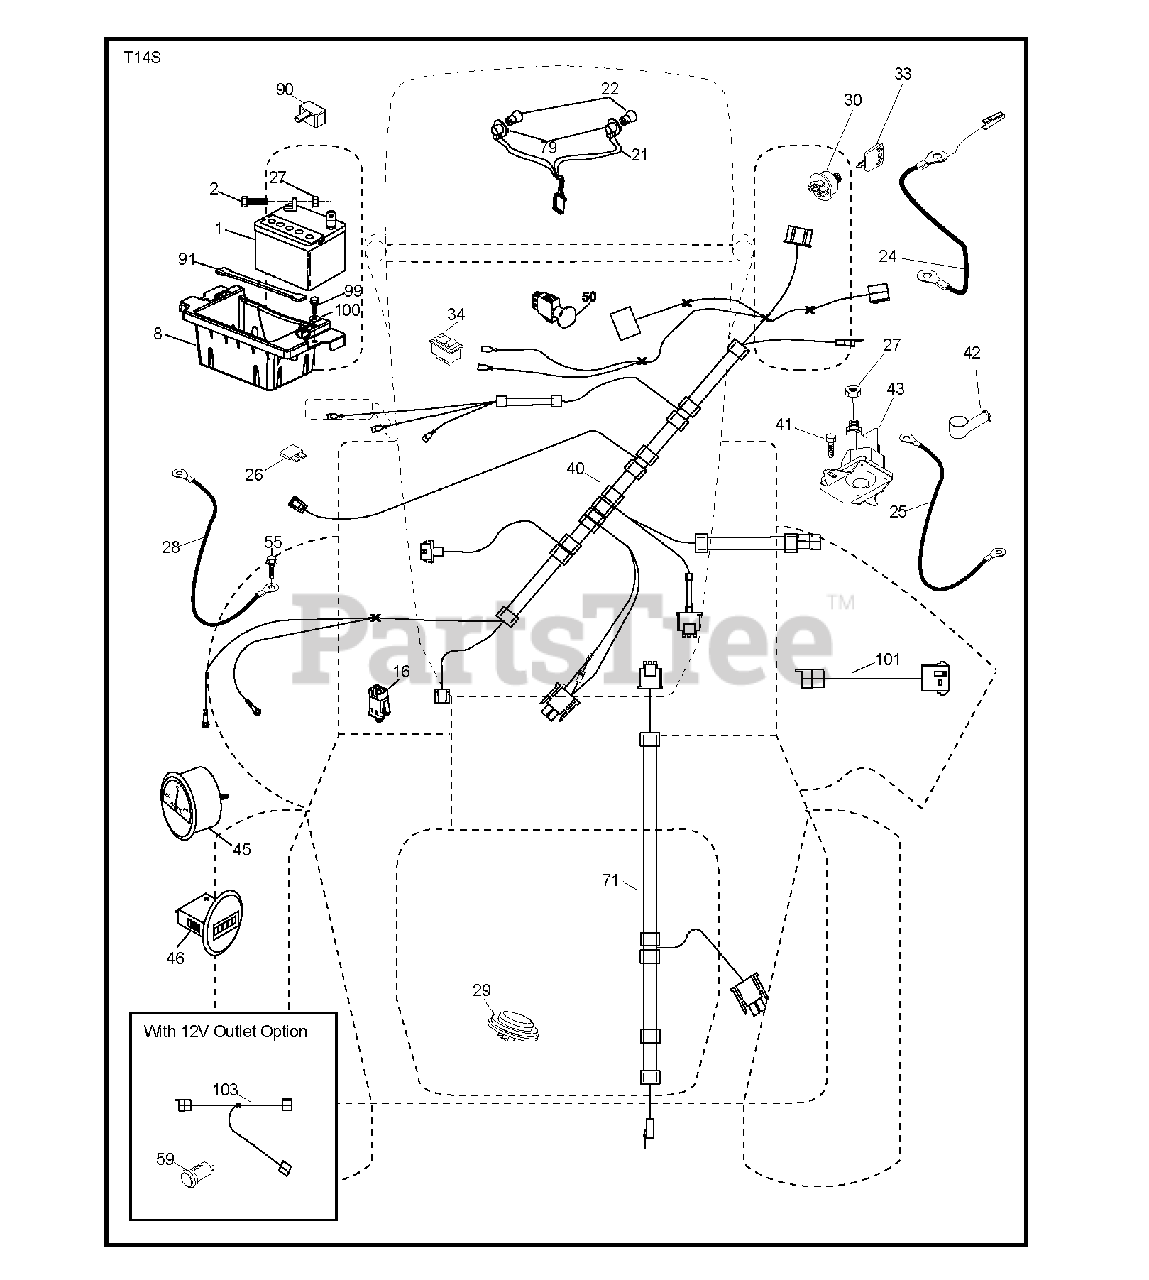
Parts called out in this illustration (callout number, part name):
1	BATTERY 12V .35 AMP
8	BOX.BATTERY.MOUNT.FRONT.LT
16	SWITCH INTERLOOK PUSH-IN
21	HARNESS.W/LIGHT SOCKET
22	LIGHTBULB
24	CABLE.BATT.POS.WIRE.TG.DA SOL
25	CABLE.START.RED.17.5".
26	FUSE 20AMP
27	NUT
28	CABLE GROUND 6 GA 21" 90T BLK
29	SWITCH.SEAT.DELTA.OPC.
30	SWITCH.IGN.DELTA.W.LGH.ROS
33	KEY.CHAIN.BLISTER.PACK.GEN.INT
34	SWITCH LT
40	HARNESS IGN. DASH
41	SCREW
42	TERMINAL COVER
43	SOLENOID.W/BRASS.PLUNG
46	HOURMETER SNAP-IN
50	PTO SWITCH
55	SCREW 5/16"
71	HARNESS-CHASSIS SUB
79	BULB HOLDER ASM.
90	COVER.TERMINAL.BATTERY
91	STRAP, BATTERY MOUNT
99	SCREW HEXWSHR 1/4-20X3/4
101	PIGTAIL.MATNLK.NEW.HAR
